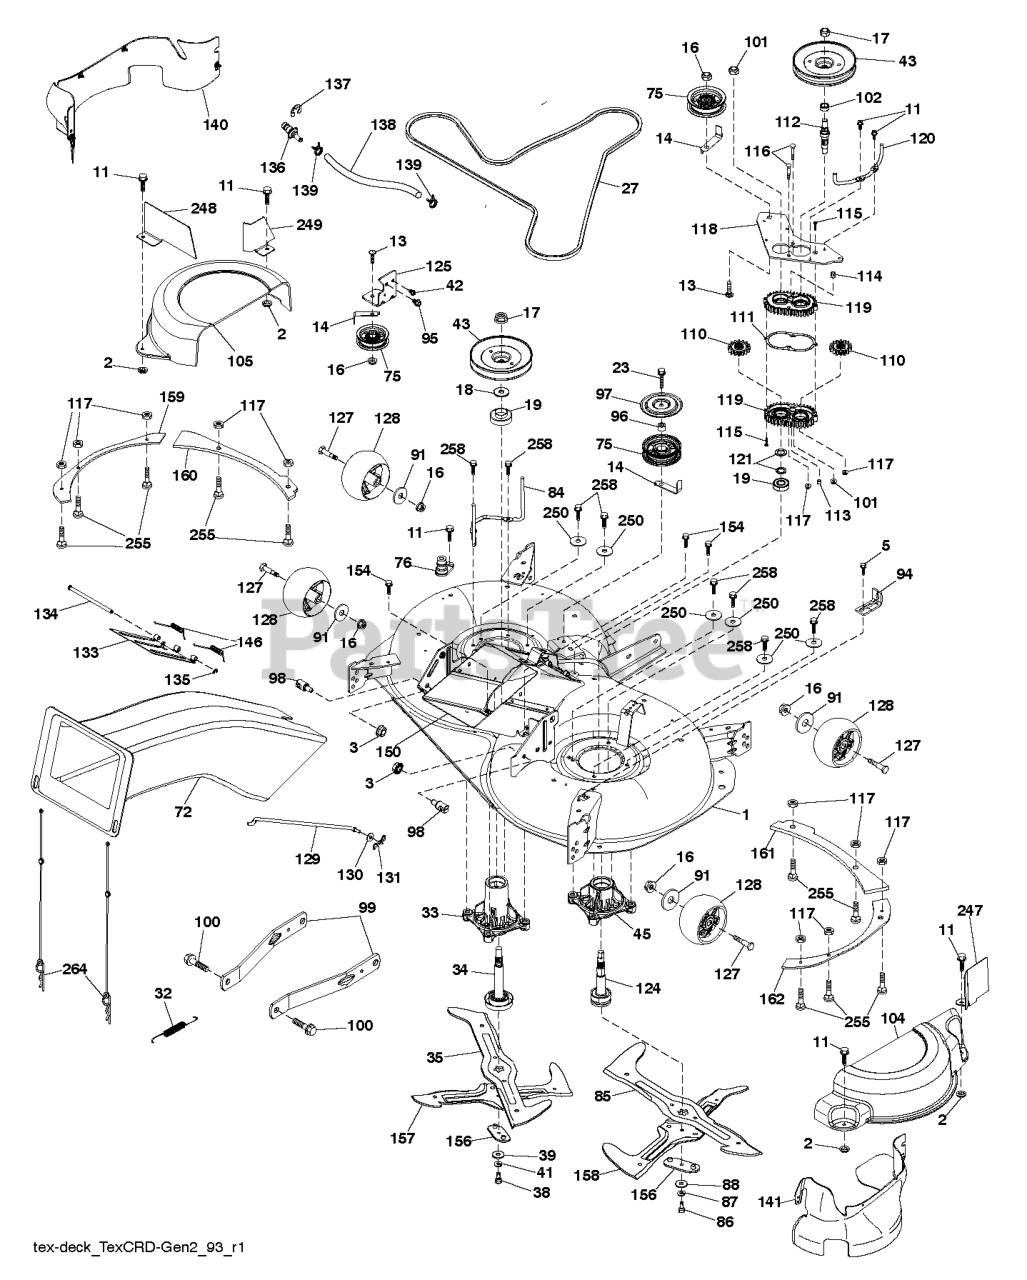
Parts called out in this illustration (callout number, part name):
1	DECK SVC 107HP.EZMUL.498
2	PALNUT 1/4
3	NUT LOCK HEX FLANGE 5/16-18
11	SCREW.1/4-20X5/8
13	BOLT.3/8-16X1.50
14	KEEPER, BELT IDLER
16	NUT LOCK FLG 3/8-16 UNC
17	NUT.FLANGE.LOCK.TOP
18	WASHER.SPACER.MANDREL
19	BEARING.MANDREL.TOP.EXTENDED
23	SCREW LT
27	BELT.ELECT.MOWER.DRIVE 97.8 EL
32	SPRING 107CM & 97CM ELECTRIC D
33	RP.HOUSG.MAND.REV.TALL.N/GRS
34	RP.SAFT ASM.REV.TALL.N/GREASE
35	BLADE.107.LH.SINGLE.NON.QD
42	SCREW
43	PULLEY PULLEY MANDREL 5.438 PD
45	RP HOUSING.MANDREL.REV.REVS.
47	SCREW.SEMS.7/16-20X1.HEX.HEAD
72	RP.CHUTE 107/97 TEX GENII
75	FLAT IDLER PULLEY
76	1/2" BARB.DECK.WASHOUT.PORT
84	KEEPER KEEPER. LH MANDREL BELT
85	BLADE.107.RH.SINGLE.NON.QD
86	BOLT.3/8-24X1.25GR8. LHTHRD
87	LOCKWASHER
88	WASHER.BLADE
91	WASHER
94	BRKT.CLUTCH.CABLE
95	SCREW, 3/8-16X3/4
96	SPACER
97	PROTECTOR
98	STUD.FASTNER.W/ANTI-ROTATE
99	ARM.SUSPENSION.MOWER.R
100	BOLT.SHOULDER
101	NUT.CROWNLOCK.9/16 -18.UNC
102	SPACER BEARING
104	COVER.MANDREL.107.RH.GEN.2
105	COVER.MANDREL.107.LH.GEN.2
110	CRD.SPUR.GEAR
111	GASKET GASKET GEARCASE
112	SHAFT SHAFT. CRD GEARCASE ADAP
113	PLUG PLUG OIL
114	VENT.BREATHER.1/8 NPT
115	SCREW
116	BOLT.CARIGE.SS.1/4-20X1.75GR5
117	NUT T
118	ARM ARM. CLUTCHING 107 TEX CRD
119	GEARCASE GEARCASE SUBASM
120	KEEPER KEEPER. RH MANDREL BELT
121	WASHER WASHER
124	SUB.ASM.REVERSE.THREAD.REV
125	BRACKET BRACKET IDLER CHASSES
127	BOLT.SHOULDER.3/8-16X3-5/8.
128	RP WHEEL. GUAGE RALLY
129	ROD ROD. SWAY CRD GEN II
130	WASHER
131	PIN.COTTER.5/16.BOW TI
133	COVER DOOR.107 CM CRD EZ MULCH
134	PIN PIN.HINGE
135	E-RING.5/16"
136	PLUG WASHOUT PORT HOOKUP
138	107.WASHOUT.PORT.HOSE (2 2)
139	HOSE.3/8.CLAMP (2 2)
140	GUARD.ASSEMBLY.107.LH.FRENCH
141	GUARD.ASSEMBLY.107.RH.FRENCH
146	SPRING SPRING: EZ MULCH DOOR
154	SCREW T-30 1/4-20 X
159	REINFORCE.PLATE.LH.FT.X431
160	REINFORCE.PLATE.LHS.BOLT.431
161	REINFORCE.PLATE.RH.FRT.X431
162	REINFORCE.PLAT.RH.SD.BLT.X431
247	GUARD.STEEL.CRD.MANDREL.COV.FR
248	GUARD.STEEL.CRD.MANDREL.COV.FR
249	GUARD.STEEL.CRD.MANDREL.COV.FR
255	RHSNB, 1/4-20 X 1, GR5
258	BOLT.HEX.WASHR.HED.313-18X1.19
264	RETAINER.ASM.UPPERCHUTE.CRD2.5
